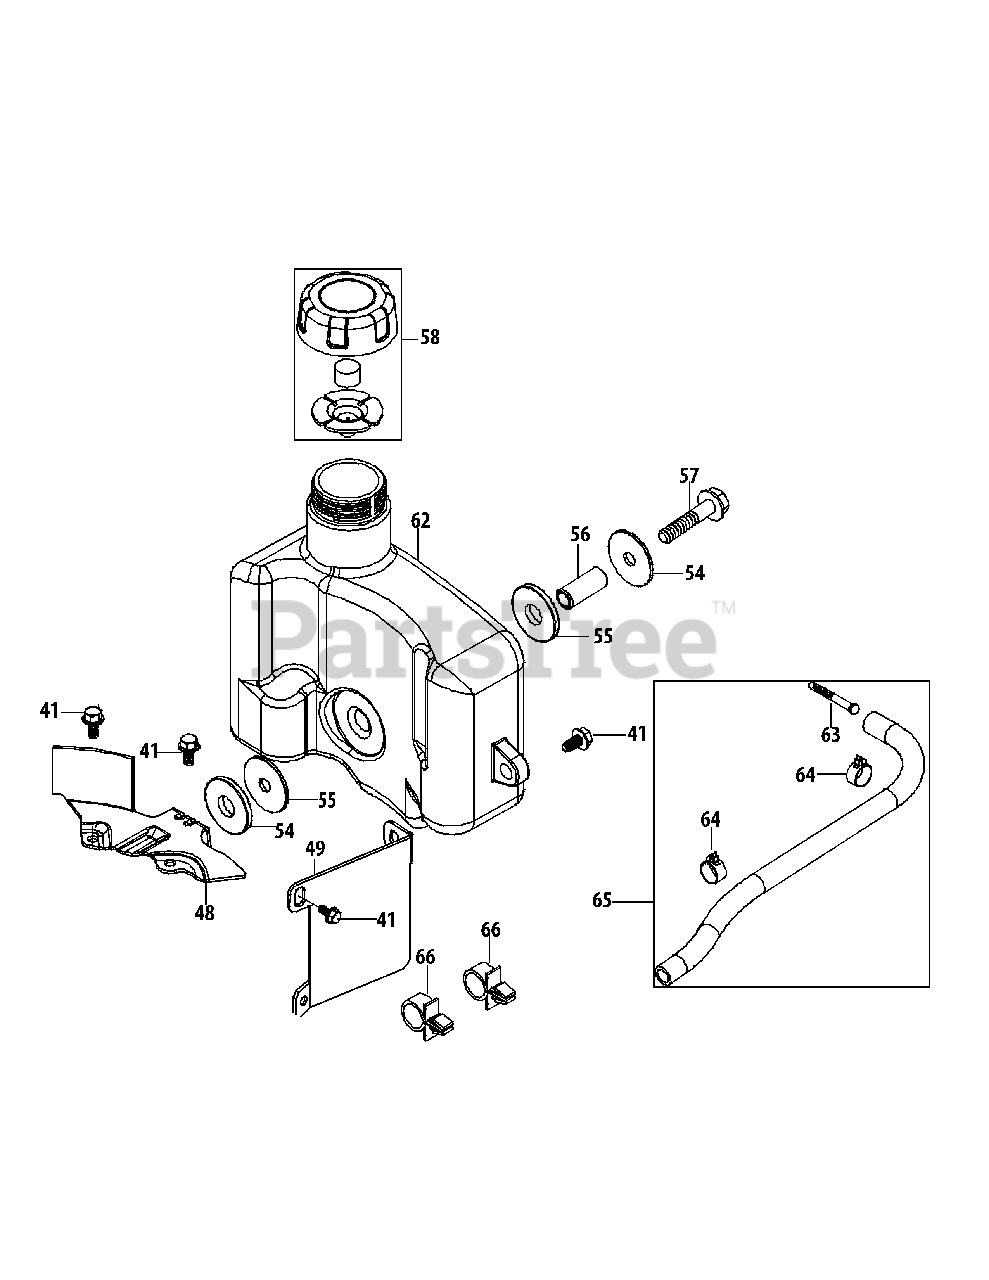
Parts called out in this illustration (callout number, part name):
41	Bolt M6X14
48	Fuel Tank Bottom Bracket
49	Fuel Tank / Label Bracket
54	Fuel Tank Washer
55	Rubber Bushing
56	Fuel Tank Bushing
57	Bolt M8X50
58	Fuel Cap Assembly
62	Fuel Tank Assembly
63	Fuel Filter
64	Fuel Hose Clamp
65	Fuel Line Kit
66	Plastic Support Clamp
